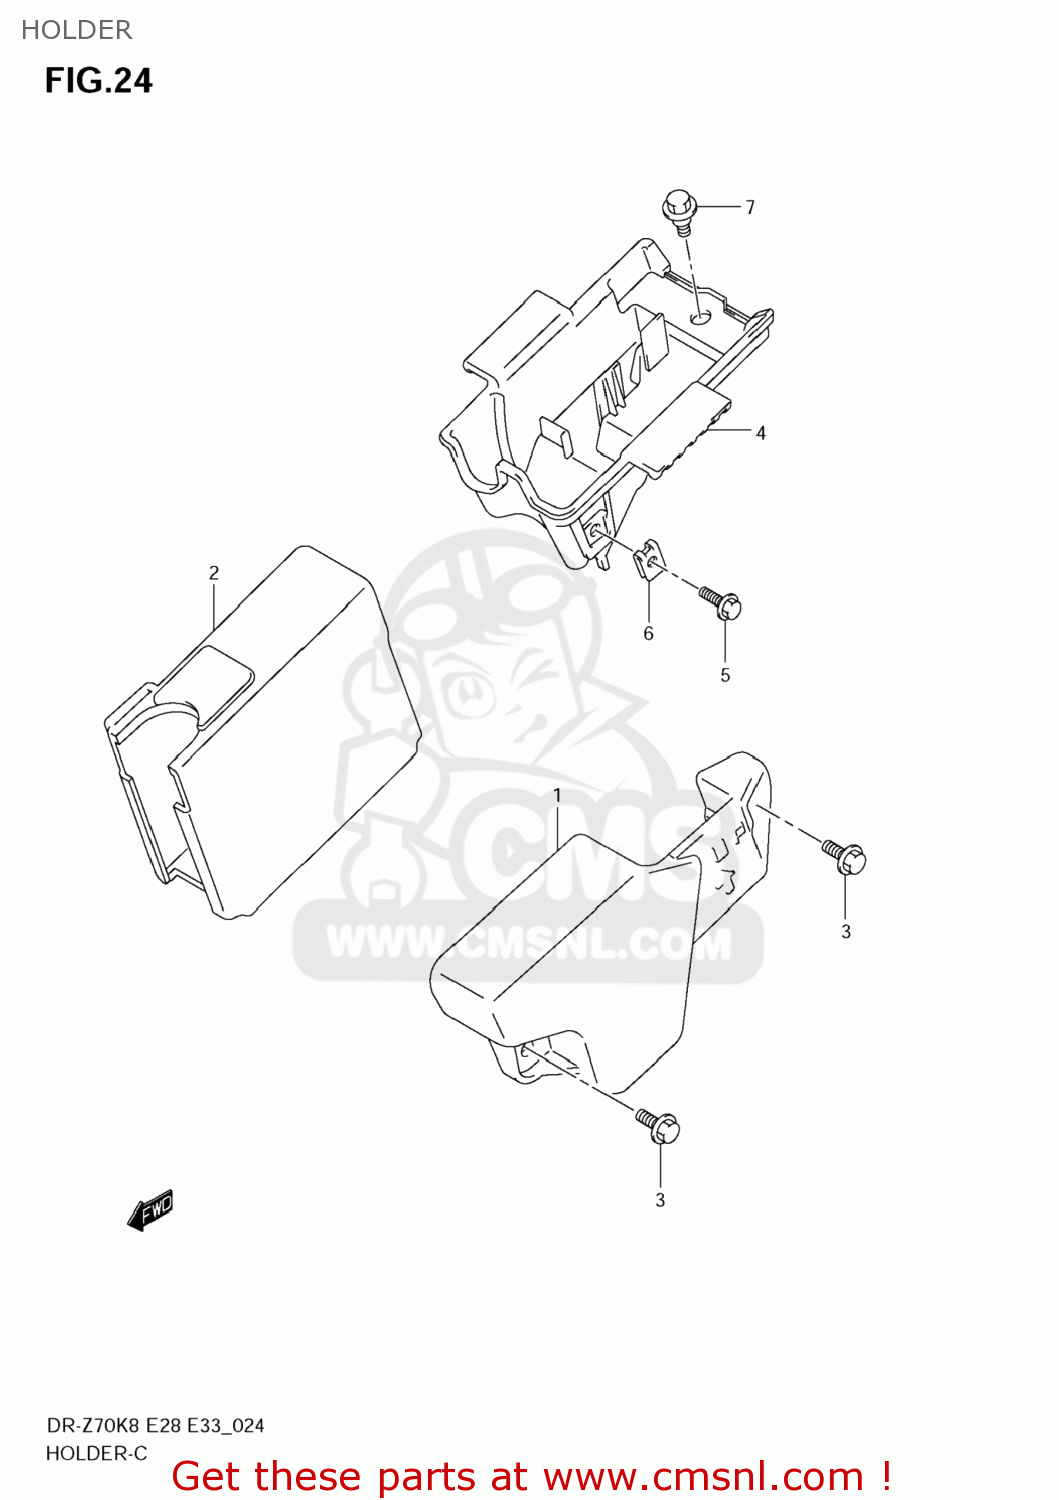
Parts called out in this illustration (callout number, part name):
1	HOLDER,BATTERY
2	RUBBER,BATTERY HOLDER
3	BOLT
4	HOLDER,ELECTRIC PARTS
5	SCREW
6	NUT
7	BOLT
